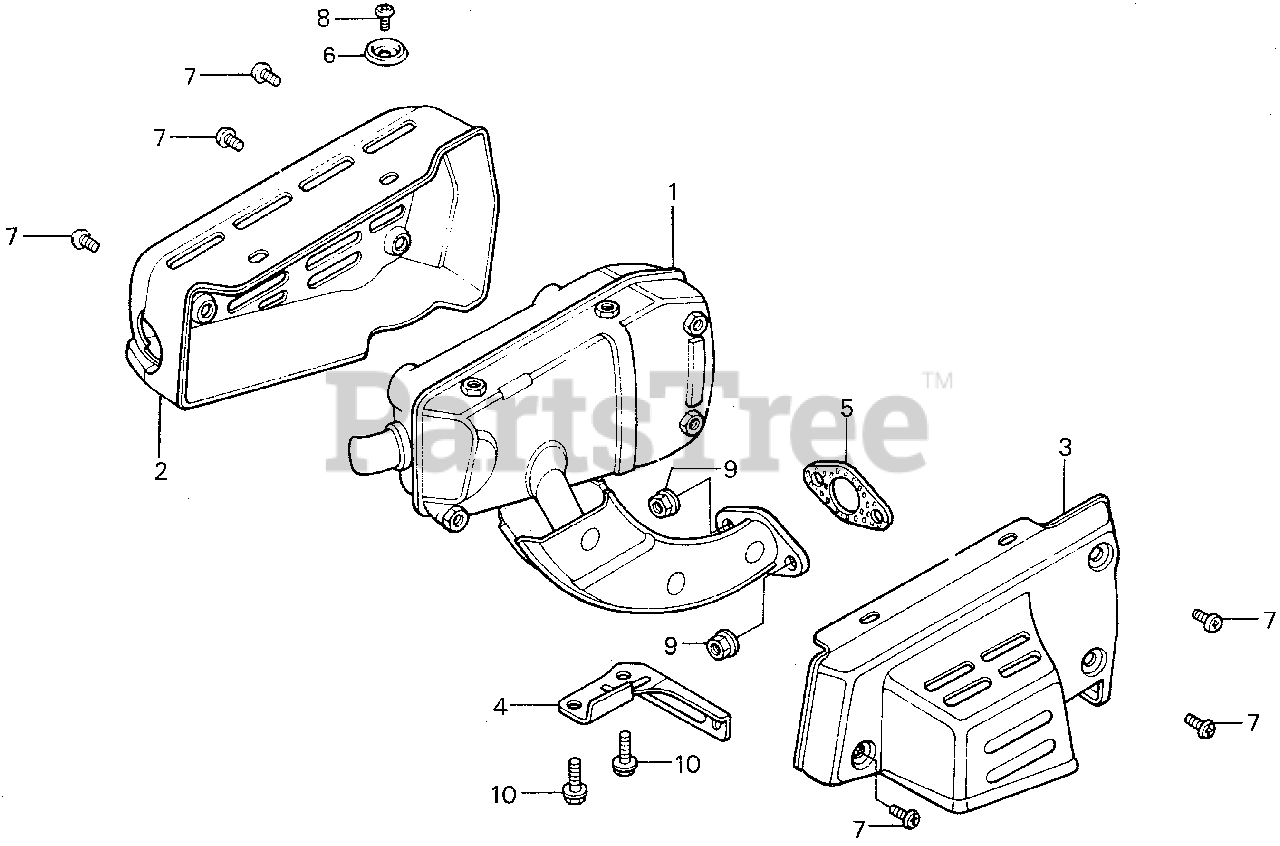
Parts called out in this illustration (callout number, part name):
2	PROTECTOR, MUFFLER
3	SEPARATOR, MUFFLER
4	STAY, MUFFLER
5	GASKET, MUFFLER
6	WASHER, MUFFLER
7	SCREW, PAN (6X6)
8	SCREW, PAN (6X8)
9	NUT, FLANGE (8MM)
10	BOLT, FLANGE (6X16)
